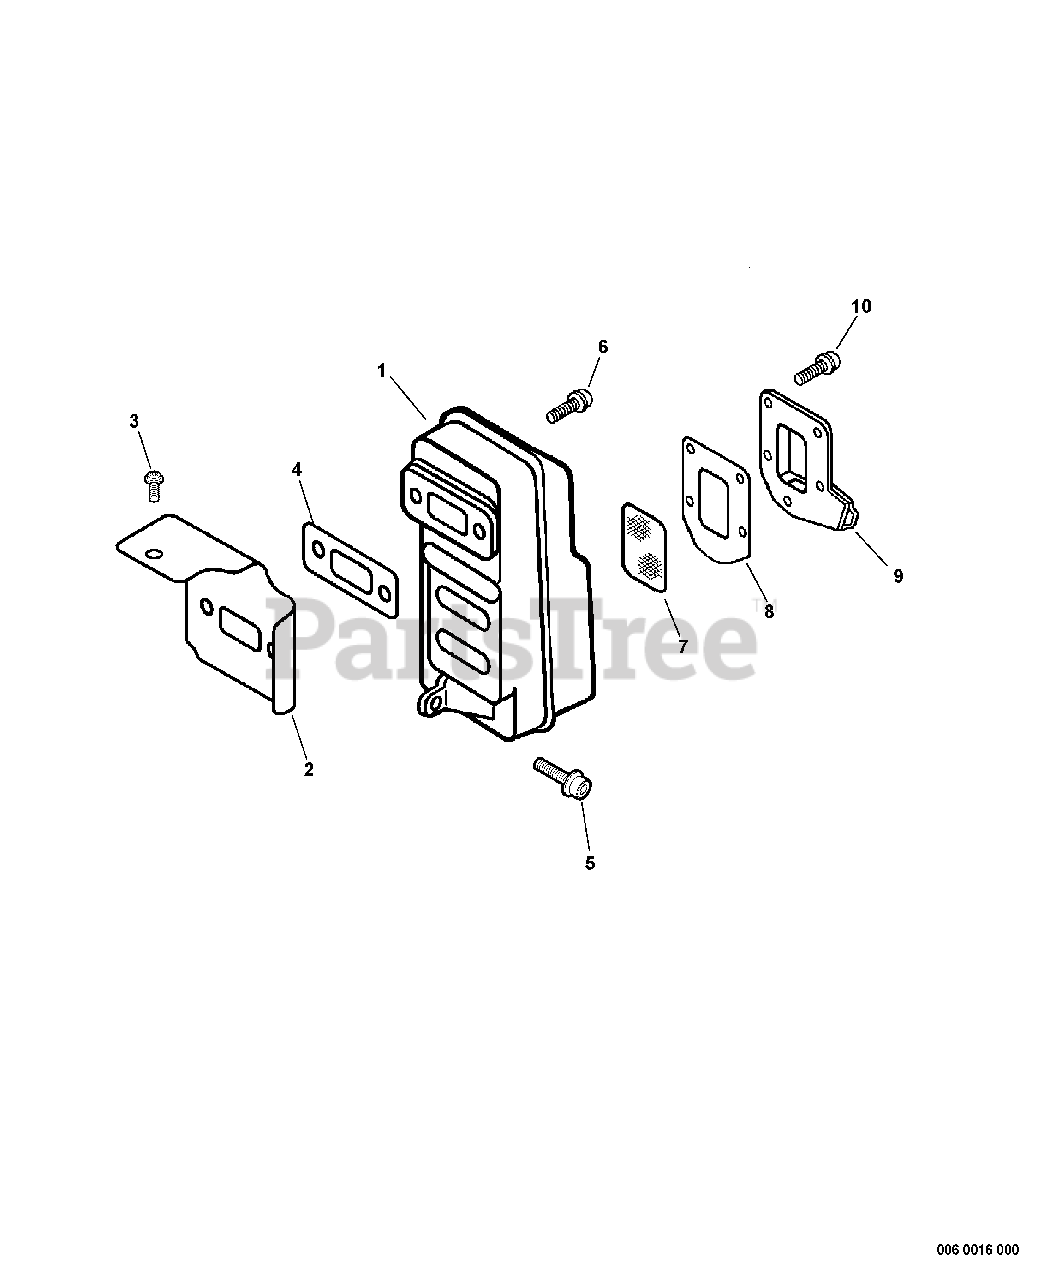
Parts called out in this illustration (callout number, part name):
1	MUFFLER
2	COVER, CYLINDER
3	SCREW 5×10
4	GASKET, EXHAUST
5	BOLT 5×20
6	BOLT 6×20
7	SCREEN, SPARK ARRESTER
8	GASKET, EXHAUST
9	GUIDE, EXHAUST
10	SCREW 4
